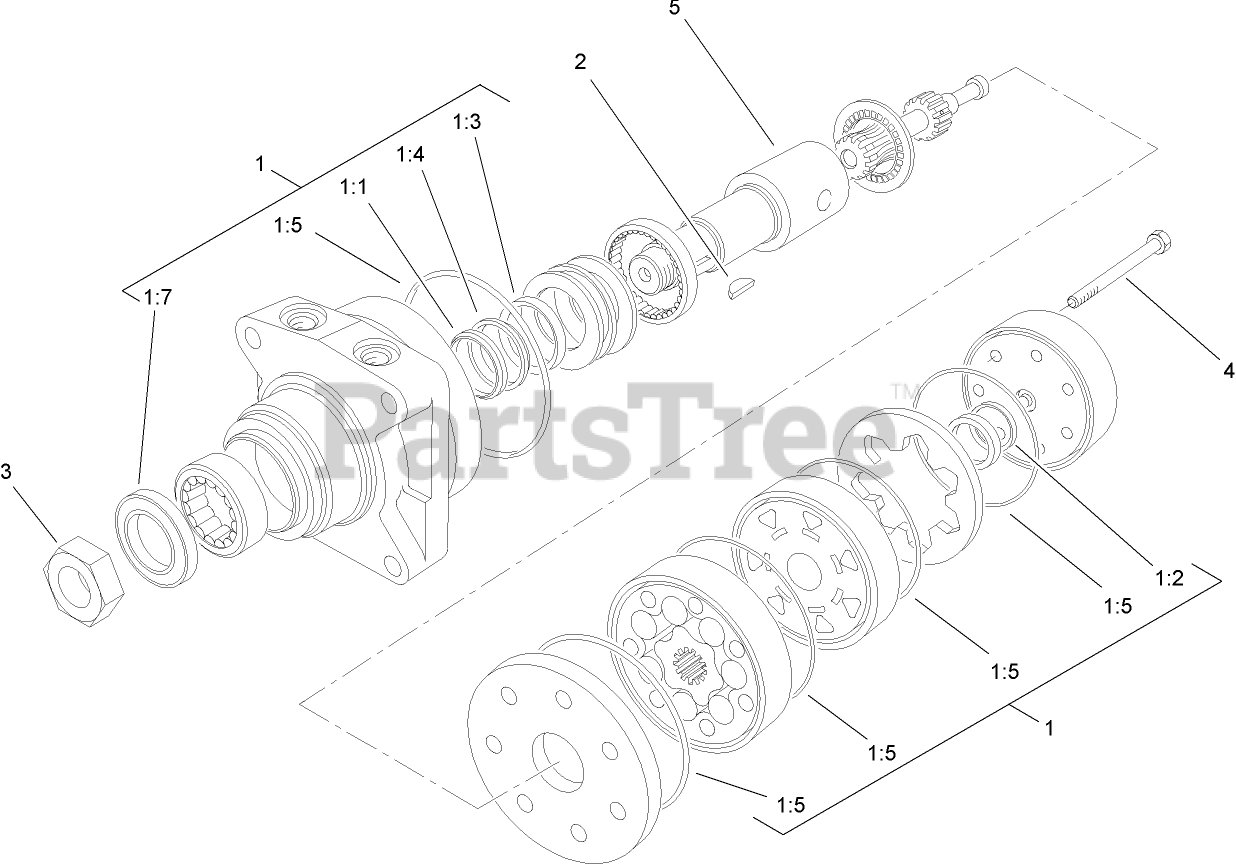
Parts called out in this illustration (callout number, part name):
1	SEAL KIT
1:1	Ring-Back Up
1:2	Seal-Commutator
1:3	SEAL-SHAFT (VITON)
1:4	WASHER-BACK UP, STEEL
1:5	RING-SEAL (VITON)
1:7	SEAL-DIRT AND WATER
2	KEY-WOODRUFF
3	NUT-MOTOR, WHEEL
4	BOLT-SPECIAL
5	SHAFT-COUPLING
